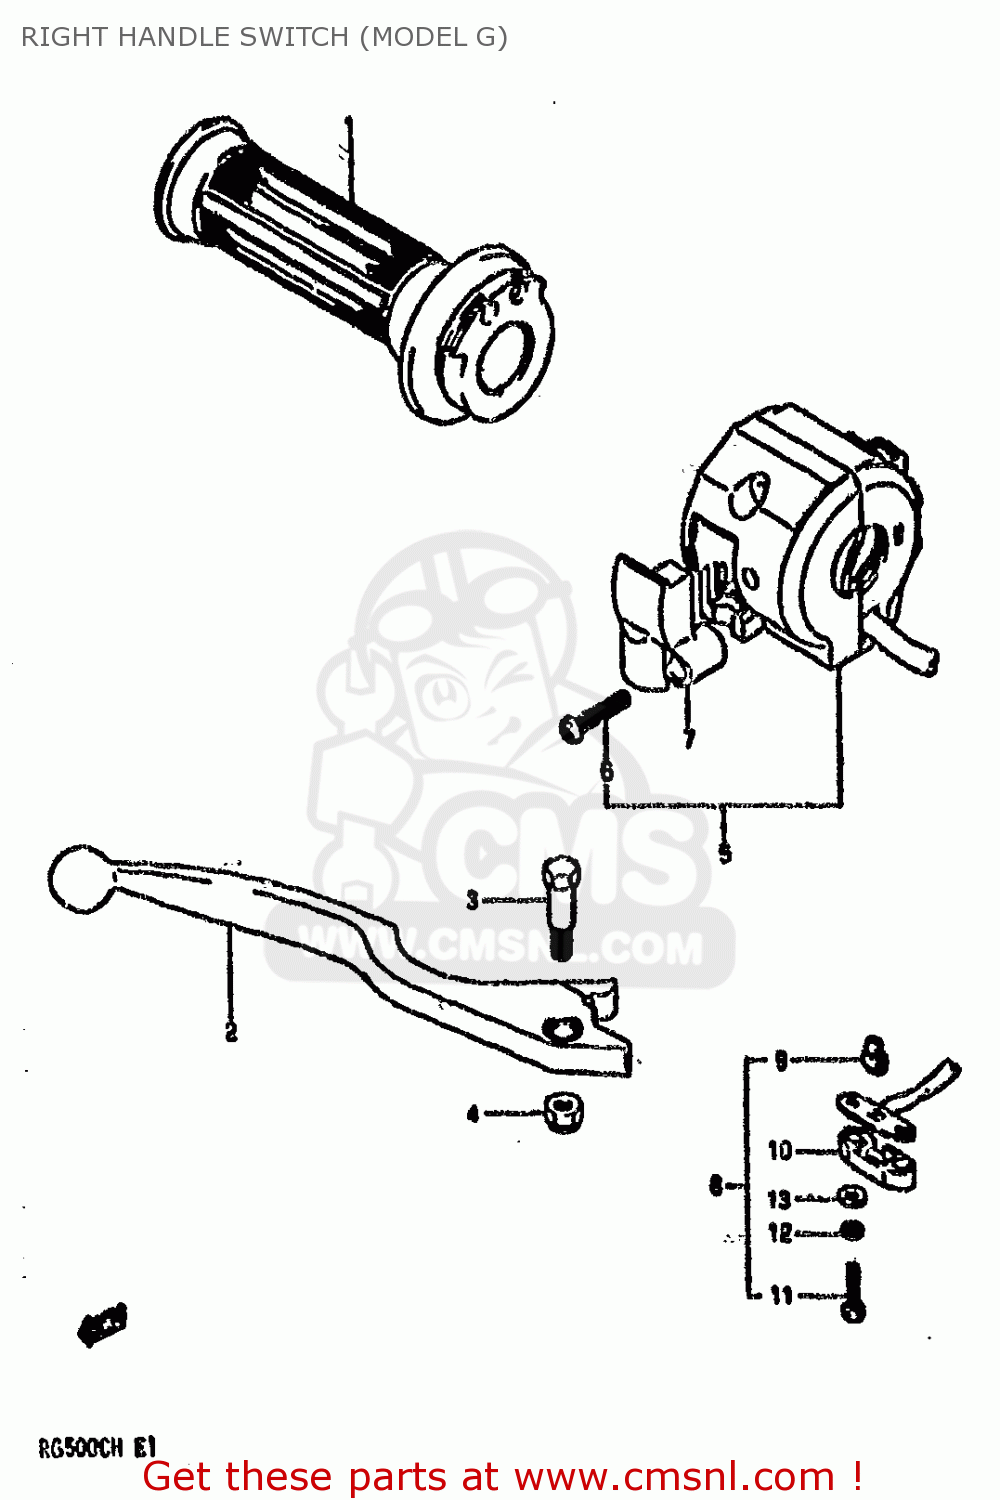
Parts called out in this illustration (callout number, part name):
1	GRIP,THROTTLE
2	LEVER,BRAKE
3	BOLT,LEVER PIVOT
4	NUT
5	SWITCH ASSY,HANDLE RH
6	SCREW 5X20
7	COVER
8	SWITCH ASSEMBLY
9	CONTACT,SWITCH
10	COVER,FR BK TERMINAL BASE
11	SCREW
12	LOCK WASHER
13	WASHER
